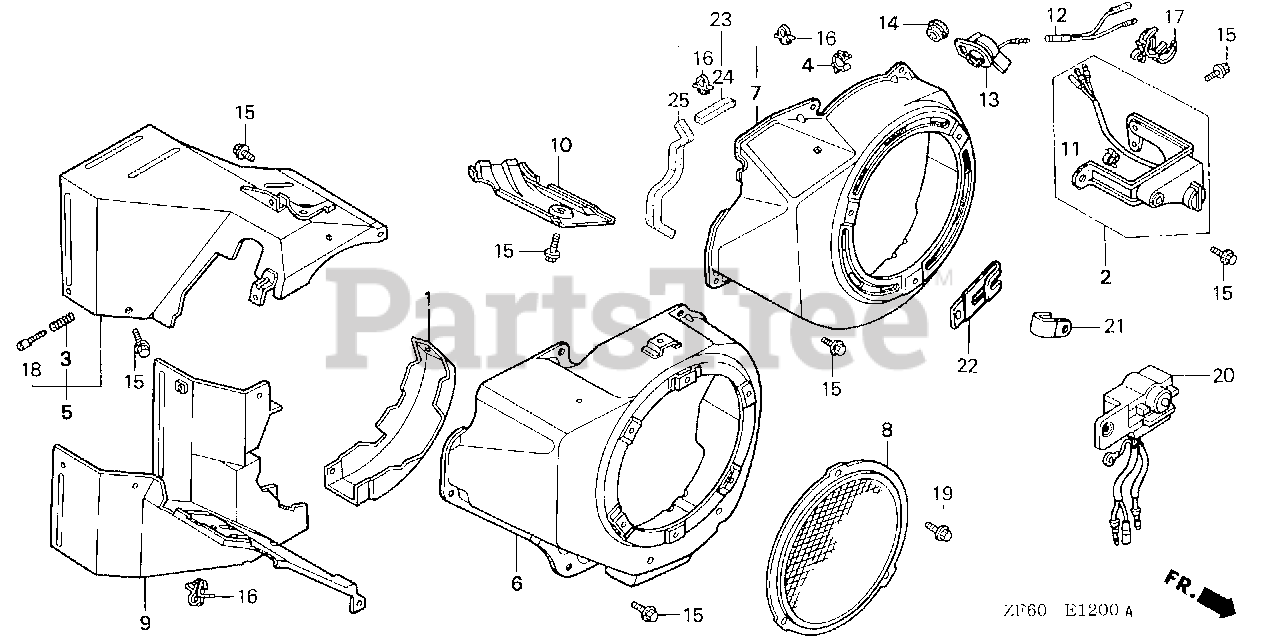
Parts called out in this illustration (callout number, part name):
4	CLIP, TUBE
7	COVER, FAN *NH246* (LOOSY GRAY)
7	COVER, FAN *R280* (POWER RED)
12	SUB-HARNESS
13	SWITCH ASSY., ENGINE STOP
15	BOLT, FLANGE (6X12) (CT200)
17	CLIP, HARNESS
